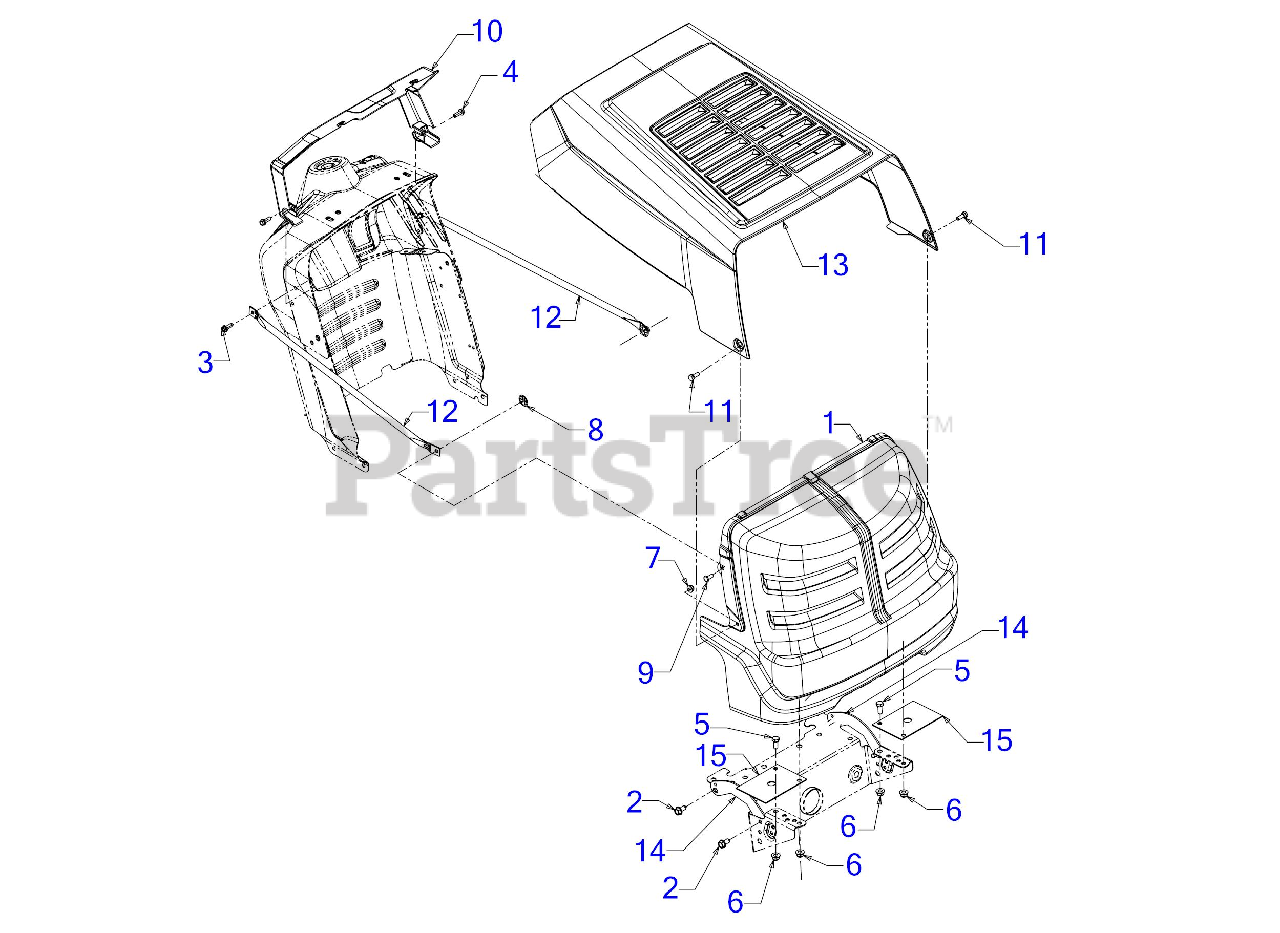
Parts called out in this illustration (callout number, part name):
1	GRILLE ASSEMBLY
2	SCREW 5/16-18 x .750
3	SCREW 1/4-20 x .750
4	SCREW 1/4-15 x .750
5	SCREW 5/16-18 x .75 GR5
6	FLANGE LOCK NUT 5/16-18
7	FLANGE LOCK NUT
8	PUSH ON NUT
9	FLAT HEAD RIVET
10	DASH COLLAR
11	SHOULDER SCREW
12	GRILLE SUPPORT ROD
14	PIVOT SUPPORT BRACKET
15	SUPPORT BRACKET
